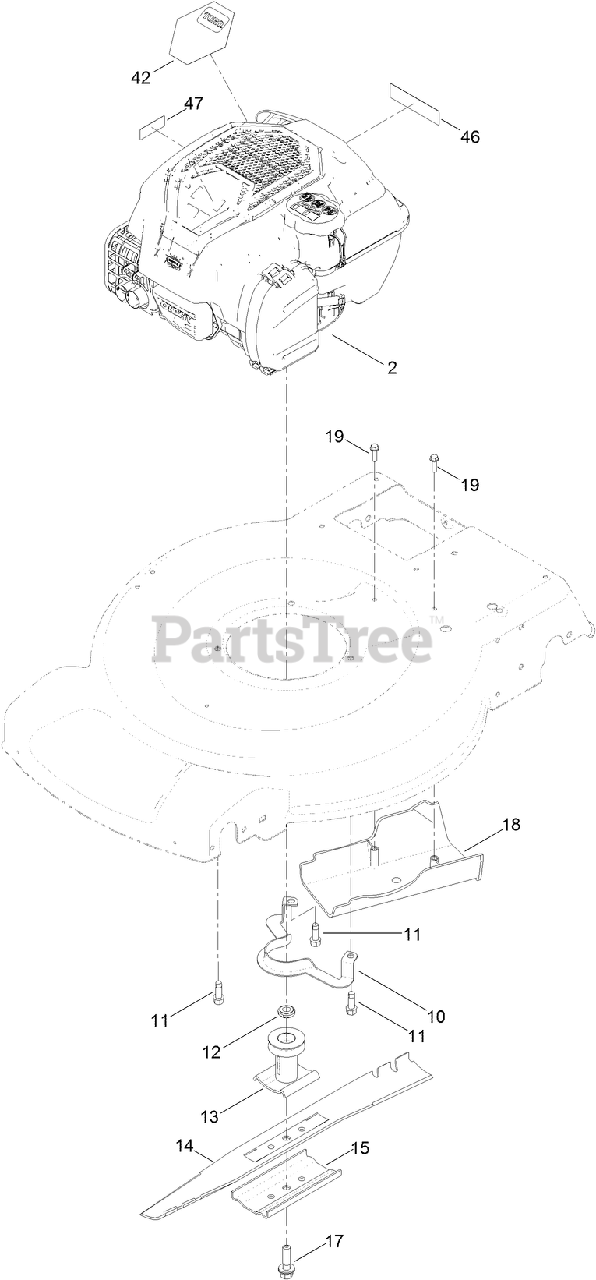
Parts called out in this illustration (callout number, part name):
10	GUIDE-BELT
11	SCREW-TAPTITE
12	SPACER-DRIVER
13	DRIVER-BLADE
14	BLADE-22 INCH
15	SUPPORT-BLADE
17	BOLT-BLADE
18	COVER-BELT
19	SCREW-HWH
42	DECAL-SHROUD
46	DECAL-ARRESTER, SPARK
47	DECAL-LEVEL, FUEL
